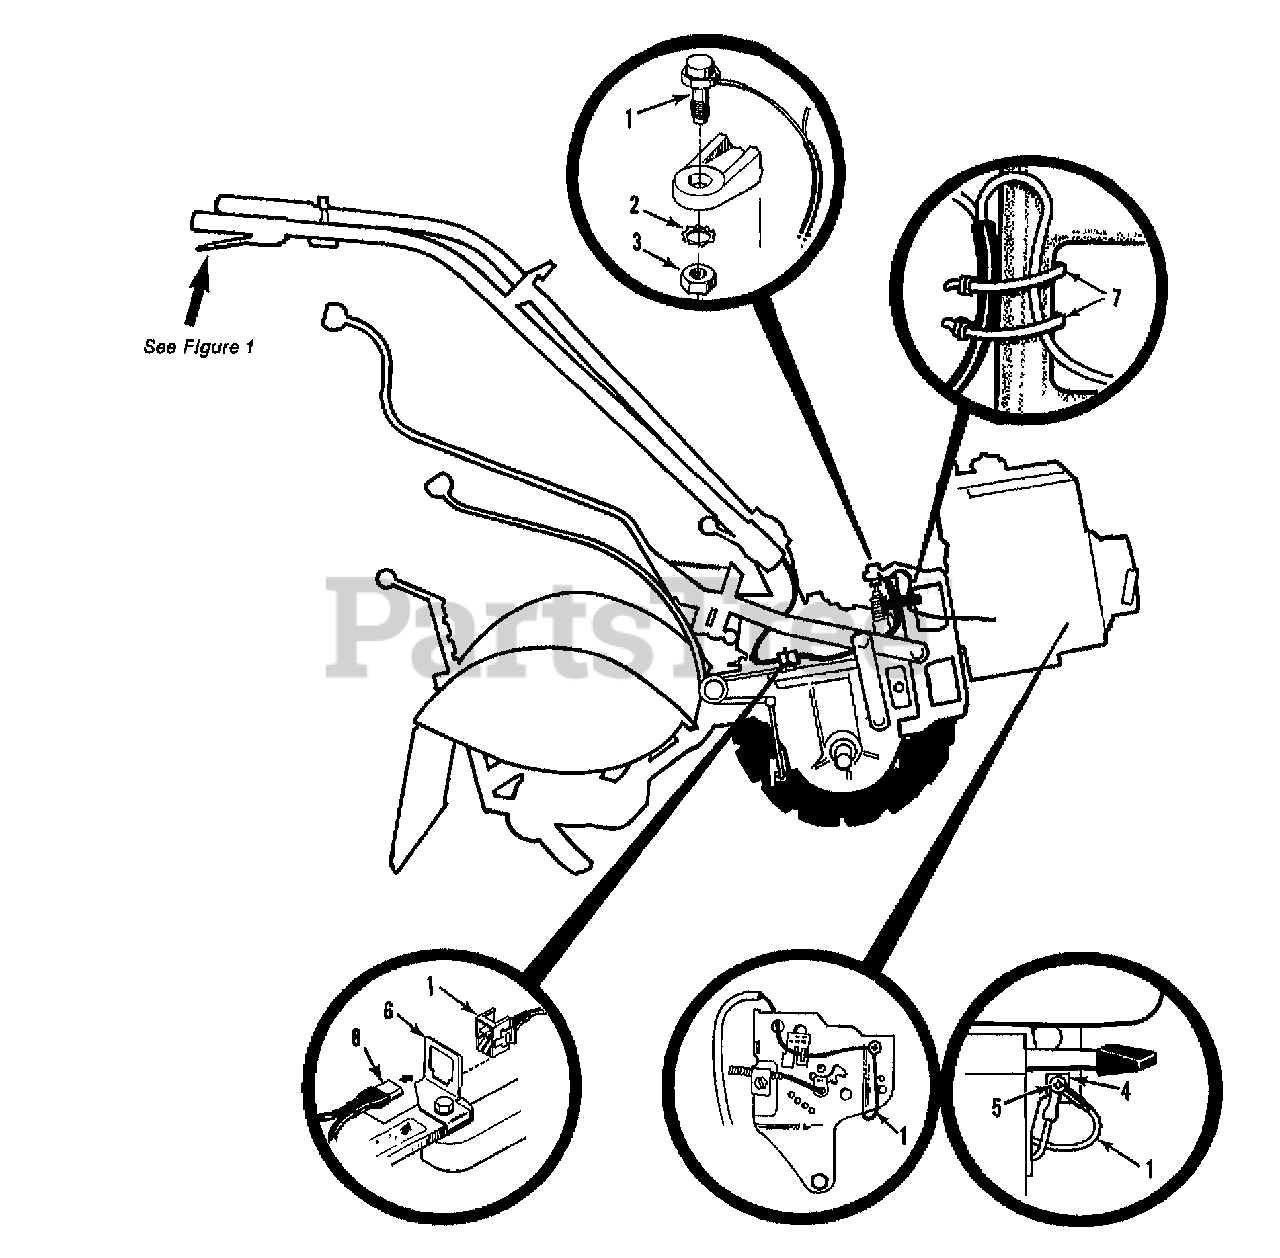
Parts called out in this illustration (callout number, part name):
1	HARNESS-WIRE ENG OPC
2	WASHER-LK .438 EXT TOOTH
3	NUT-HEX/JAM 7/16-20
4	GROMMET-7 T/L & 8 KOH OPC
5	SCR #8-18 SELF TAP
6	CLIP-CONNECTOR
7	TIE-RED
8	HARNESS-WIRE OPC HORSE
